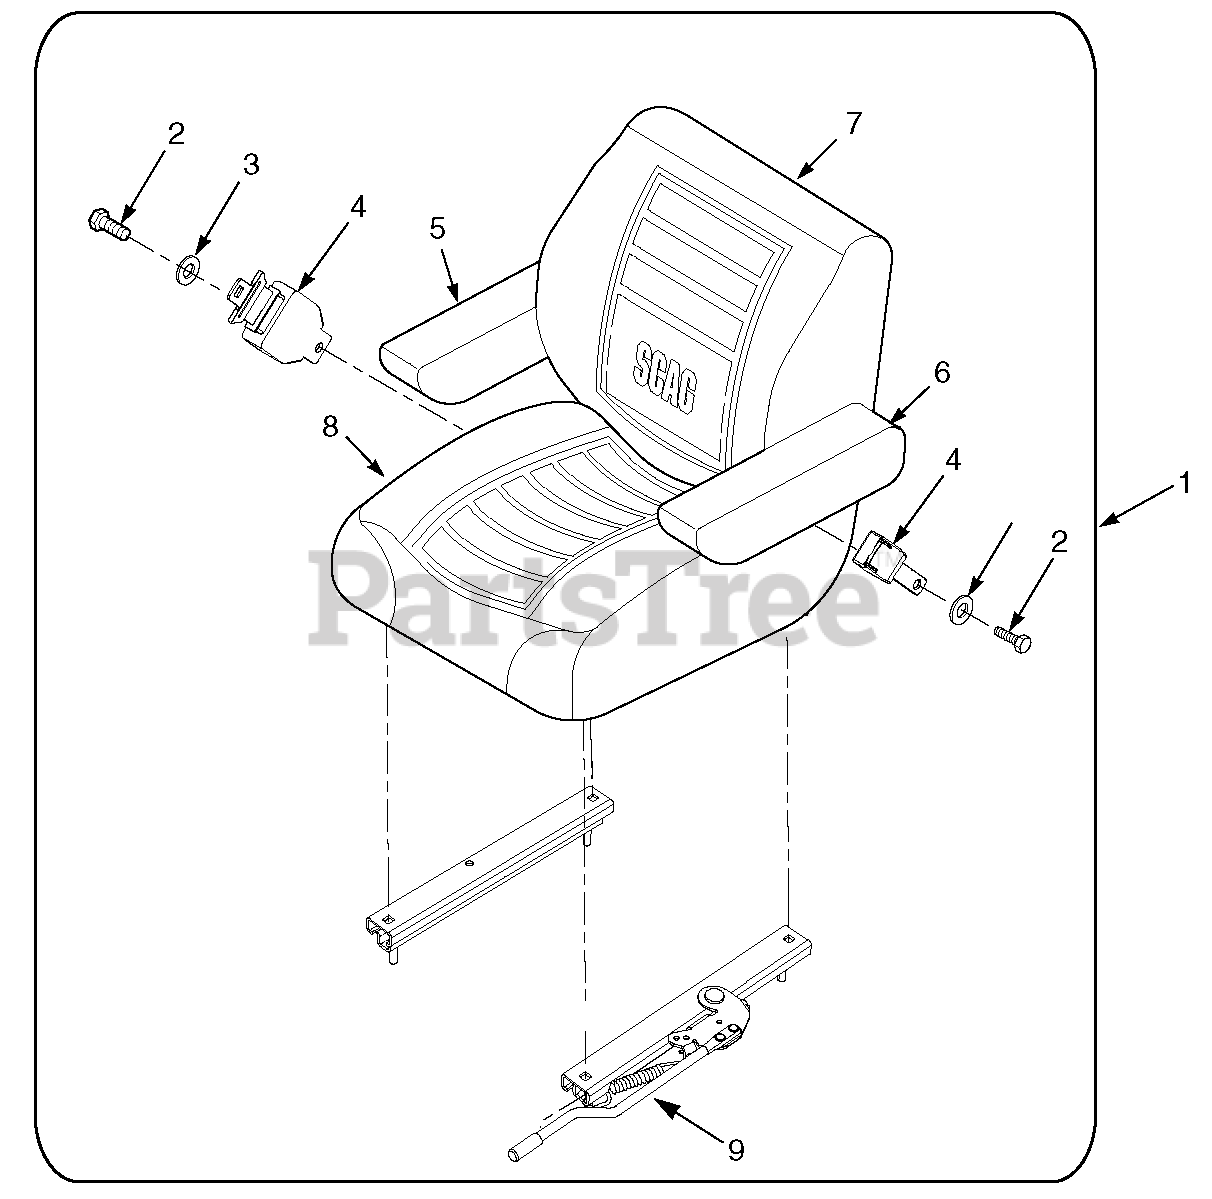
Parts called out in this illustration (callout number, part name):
1	Seat Assembly
2	Bolt, Hex Head 7/16-20 x 1"
3	Flatwasher, 7/16-.500 x 1.25 x .083
4	Retractable Seat Belt
5	Armrest, RH
6	Armrest, LH
7	Cover, Backrest
8	Cover, Cushion
9	Seat Track Set
